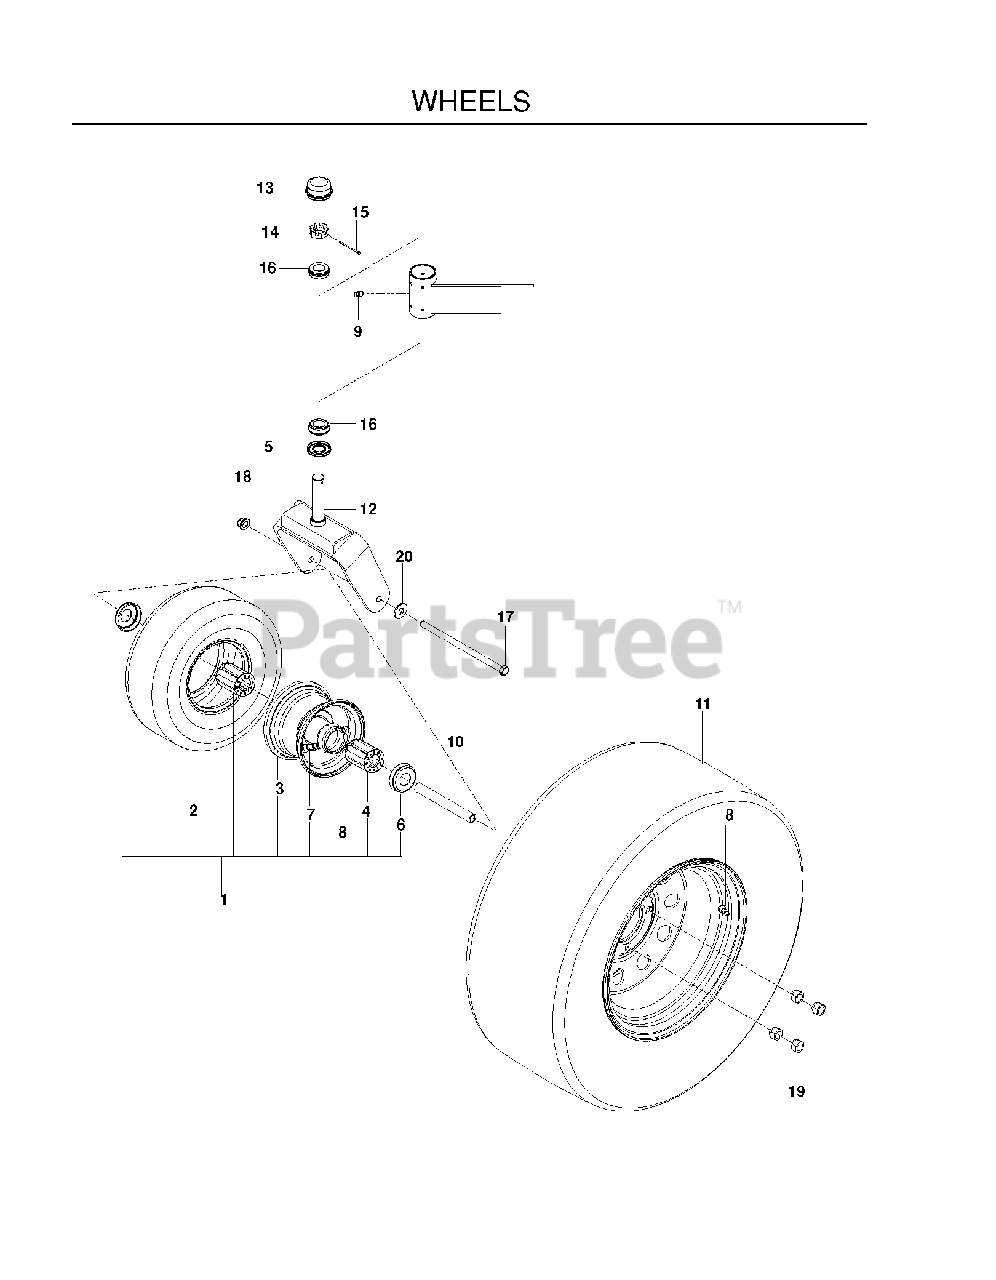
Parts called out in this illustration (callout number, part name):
1	TIRE.ASSEM.13X5-6.SMOOTH.SILVE
2	TIRE - FRONT
3	RIM
4	ROLLER BEARING
5	BEARING RETAINER
6	TAPERED ROLLER BRG
7	VALVE STEM TR-412
8	NUT 10-24 NYLOC
10	SPACER, CASTER
11	TIRE/WHEEL.ASM.22X9.5-10
12	CASTER YOKE ORANGE
13	GREASE CAP
14	NUT 1"C HEX SLOTTED
15	COTTER PIN 1/8 X 2
17	SCREW 1/2C X 7 1/2 HEX CAP
18	NUT, 1/2-13 HEX FLG NYLOC ZD
19	LUG NUT 1/2F
20	WASH USS FLAT 1/2
